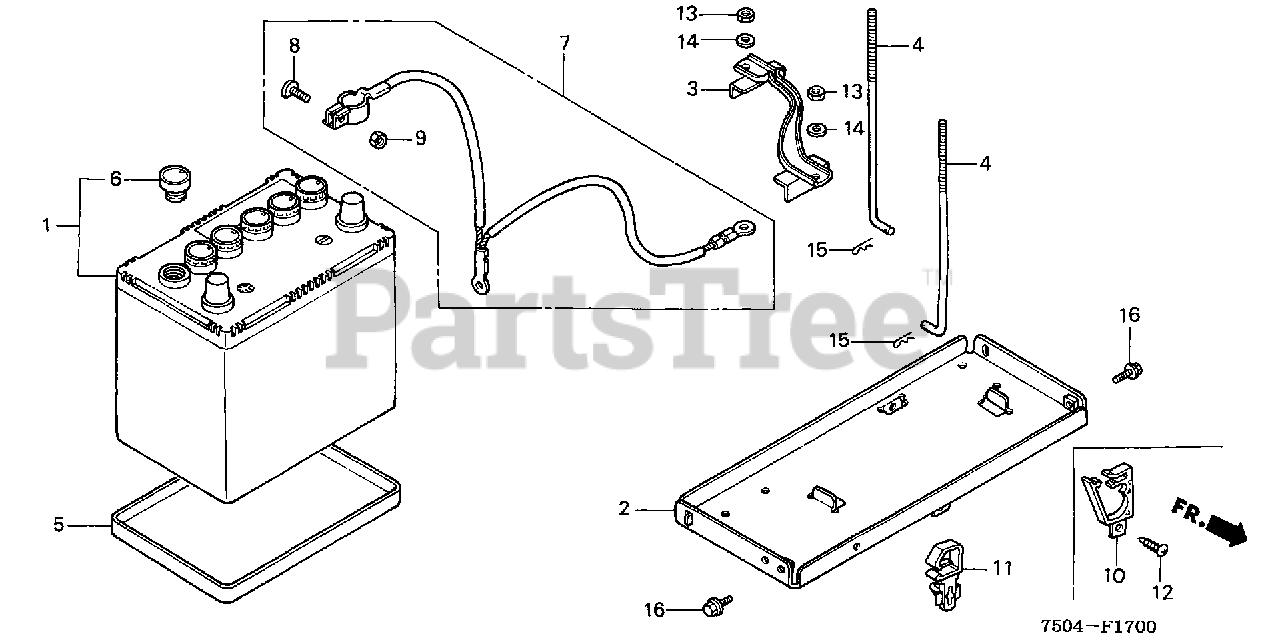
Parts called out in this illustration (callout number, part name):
1	BATTERY ASSY. (32A19RT-S) (YUASA)
2	HOLDER, BATTERY
3	PLATE, BATTERY SETTING
4	BOLT, BATTERY SETTING
5	TRAY, BATTERY
6	PLUG, VENT (YUASA)
11	CLIP, HARNESS (5MM-15MM)
13	NUT, HEX. (6MM)
14	WASHER, PLAIN (6MM)
15	PIN, LOCK (5MM)
16	BOLT, FLANGE (6X12)
